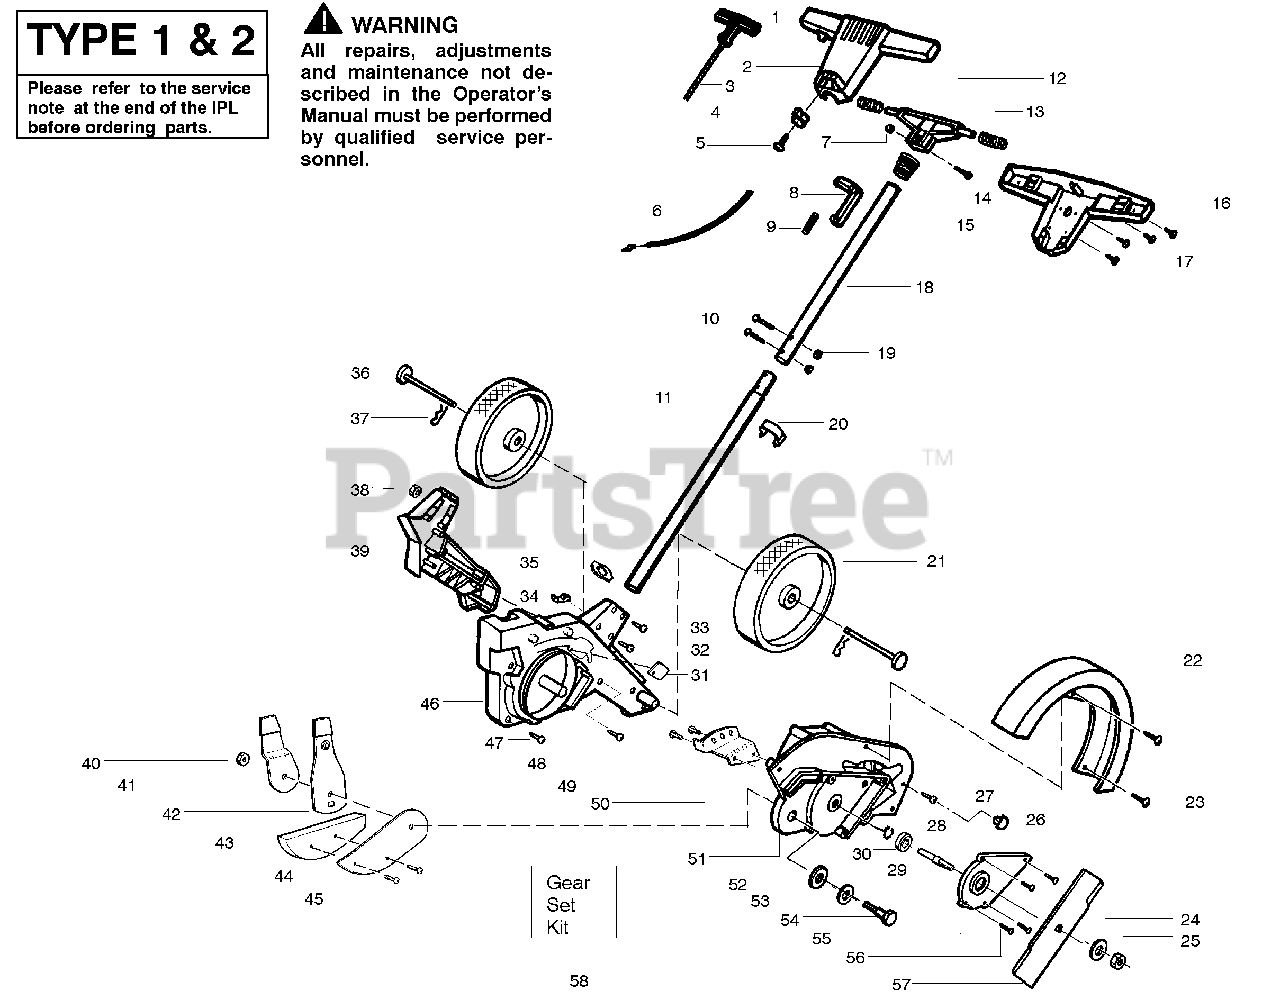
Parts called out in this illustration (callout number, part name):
1	Handle-Starter
4	Eyelet-Handle
6	Assy-Throttle Cable
8	Trigger-Throttle
9	Spring-Throttle
10	Bolt-Shoulder Tube
11	Tube-Lower Handle
12	Coupling-Handle
13	Spring-Isolator
15	Spring-Handle
18	Tube-Upper Handle
22	Shield-Front Blade
24	Washer-Belleville
27	Screw
28	Retainer Ring-Flat
30	Washer-Thrust
31	Retainer-Fuel Line
40	Nut-Swing Arm
41	Lever-Limiter
42	Assy-Lever Adjustment
51	Assy-Gear Box
52	Washer-Bolt Adjust
54	Bolt-Shoulder
55	Assy-Bearing Holder
